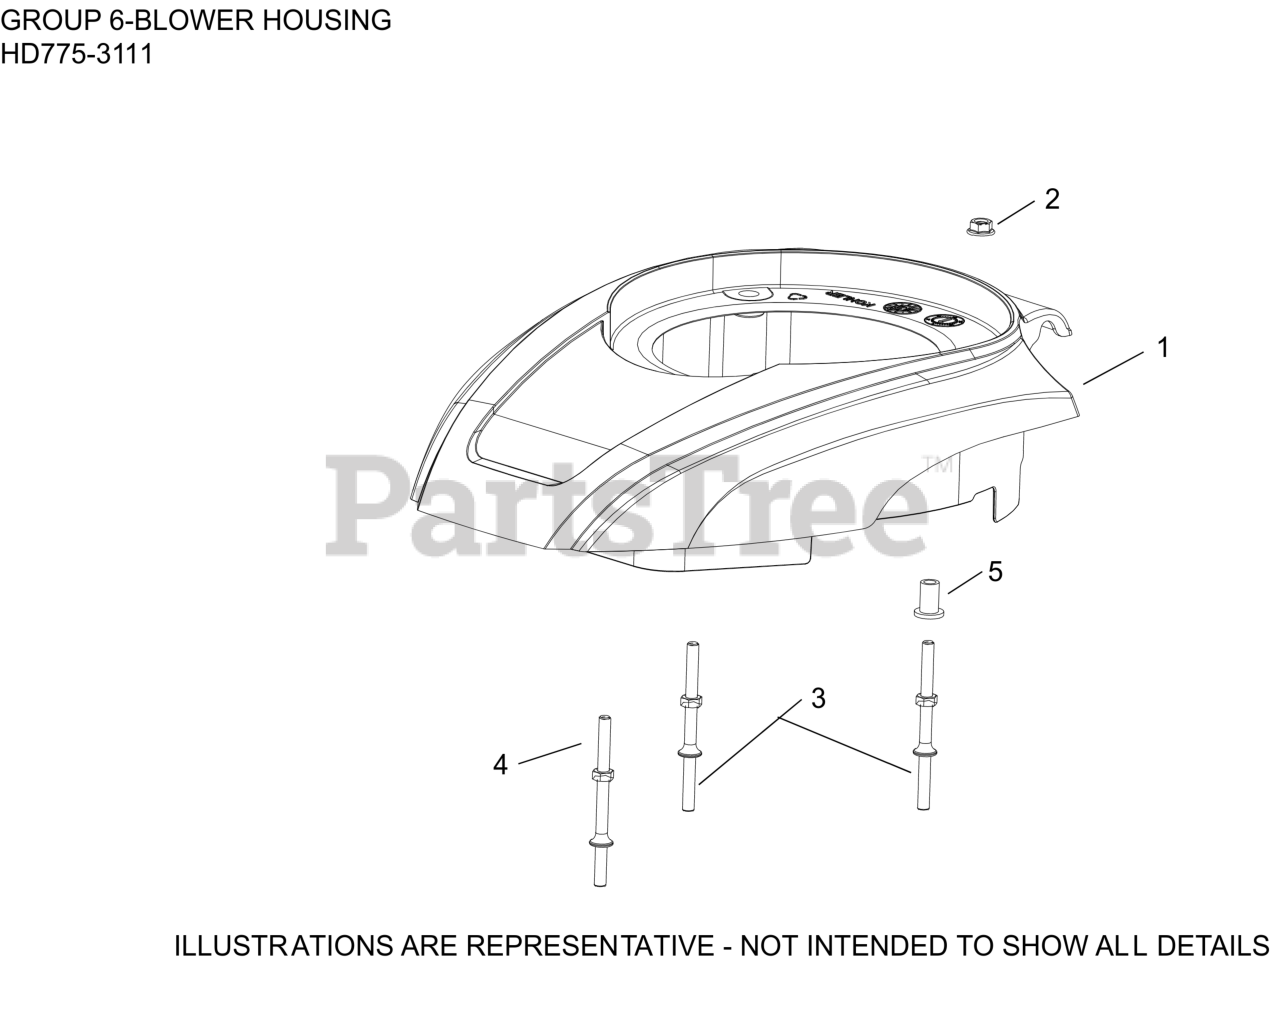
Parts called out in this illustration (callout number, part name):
1	COVER, ENGINE
2	NUT, HEX FLANGE (M6) - USE 14 100 16-S
3	STUD-USE 14 072 25-S
4	STUD-USE 14 072 26-S
